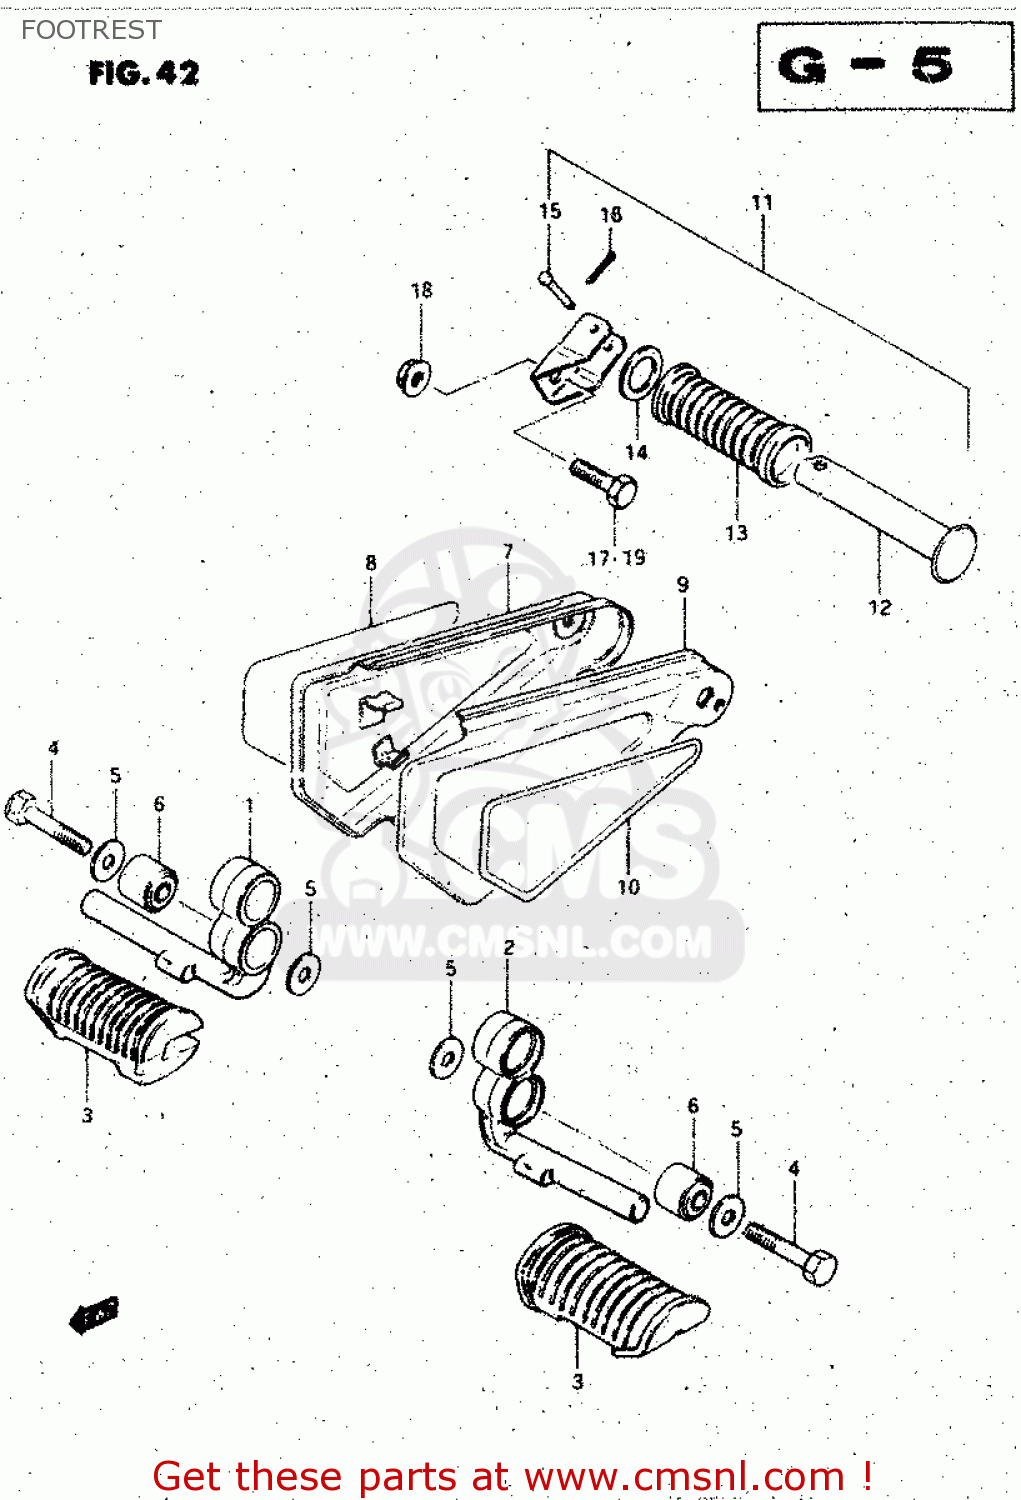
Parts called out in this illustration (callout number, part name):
1	BAR, FOOTREST RH
2	BAR,FR FOOTREST
3	RUBBER,FR FOOTREST
4	BOLT(10X35)
5	WASHER
6	BUSH(10.2X25X19)
7	COVER,FOOTREST SPRT TUBE,L
8	EMBLEM,FOOT REST COVER,R
9	COVER,FOOTREST SPRT TUBE,L
10	EMBLEM,FOOT REST COVER,L
11	FOOTREST ASSY,PILLION,R
12	BAR,FOOTREST RUBBER
13	RUBBER,PILLION FOOTREST
14	WASHER (19.5X32X2)
15	PIN
16	PIN
17	BOLT, RH
18	NUT
19	BOLT
